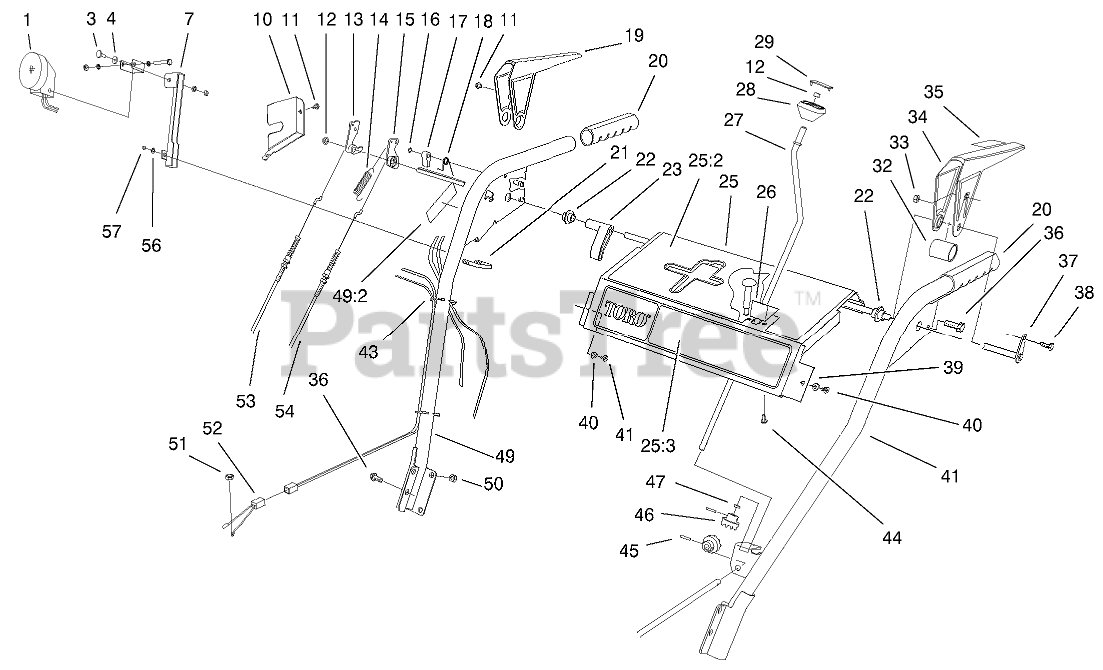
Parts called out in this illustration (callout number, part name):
3	Screw-CARR (only on: 38079)
4	Washer-Flat (only on: 38079)
7	Mount-Light (only on: 38079)
10	COVER-LOCK, LEVER
11	SCREW-HH
12	RETAINER-PUSH ON
13	TANG-LOCKING
14	SPRING-EXTENSION
15	CAM-RELEASE
16	E-RING-RETAINER
17	LATCH-LOCKING
18	SPRING-TORSION
19	LEVER-TRACTION, RH
20	GRIP-HANDLE
21	U-Bolt (only on: 38079)
22	BUSHING-LEVER
23	LEVER-TRIP
25	Control Panel ASM (only on: 38547)
25	Control Panel ASM (only on: 38079)
25:2	Decal-Top, Panel (only on: 38547)
25:2	Decal-Control (only on: 38079)
25:3	Decal-Panel, Front (924)(only on: 38079)
25:3	Decal-Panel, Front (only on: 38547)
26	PLATE-GUIDE
27	CRANK-ROD, CHUTE
28	KNOB-CONTROL, CHUTE
29	COVER-KNOB
32	SPACER-LEVER, TRACTION
33	NUT-LOCK, NI
34	LEVER-TRACTION, LH
35	Decal-Lever (only on: 38547)
36	SCREW-HWHTF
37	CROSS ROD ASM
38	SCREW-HWH
39	WASHER-FLAT
40	SCREW-HWHTF
41	LH HANDLE ASM
43	TIE-CABLE
44	SCREW
45	PIN-SPRING
46	GEAR-UNIVERSAL
47	WASHER-RUBBER
49	Handle ASM (only on: 38079)
49	Handle ASM (only on: 38547)
49:2	Decal-Adjustment (only on: 38079)
49:2	Decal-Warning (only on: 38547)
50	NUT-LOCK, NI
51	Nut-Hex (only on: 38079)
52	Wire ASM (only on: 38079)
53	CABLE-IMPELLER
54	CABLE-TRACTION
56	Washer-Flat (only on: 38079)
57	Nut-Lock, NI (only on: 38079)
